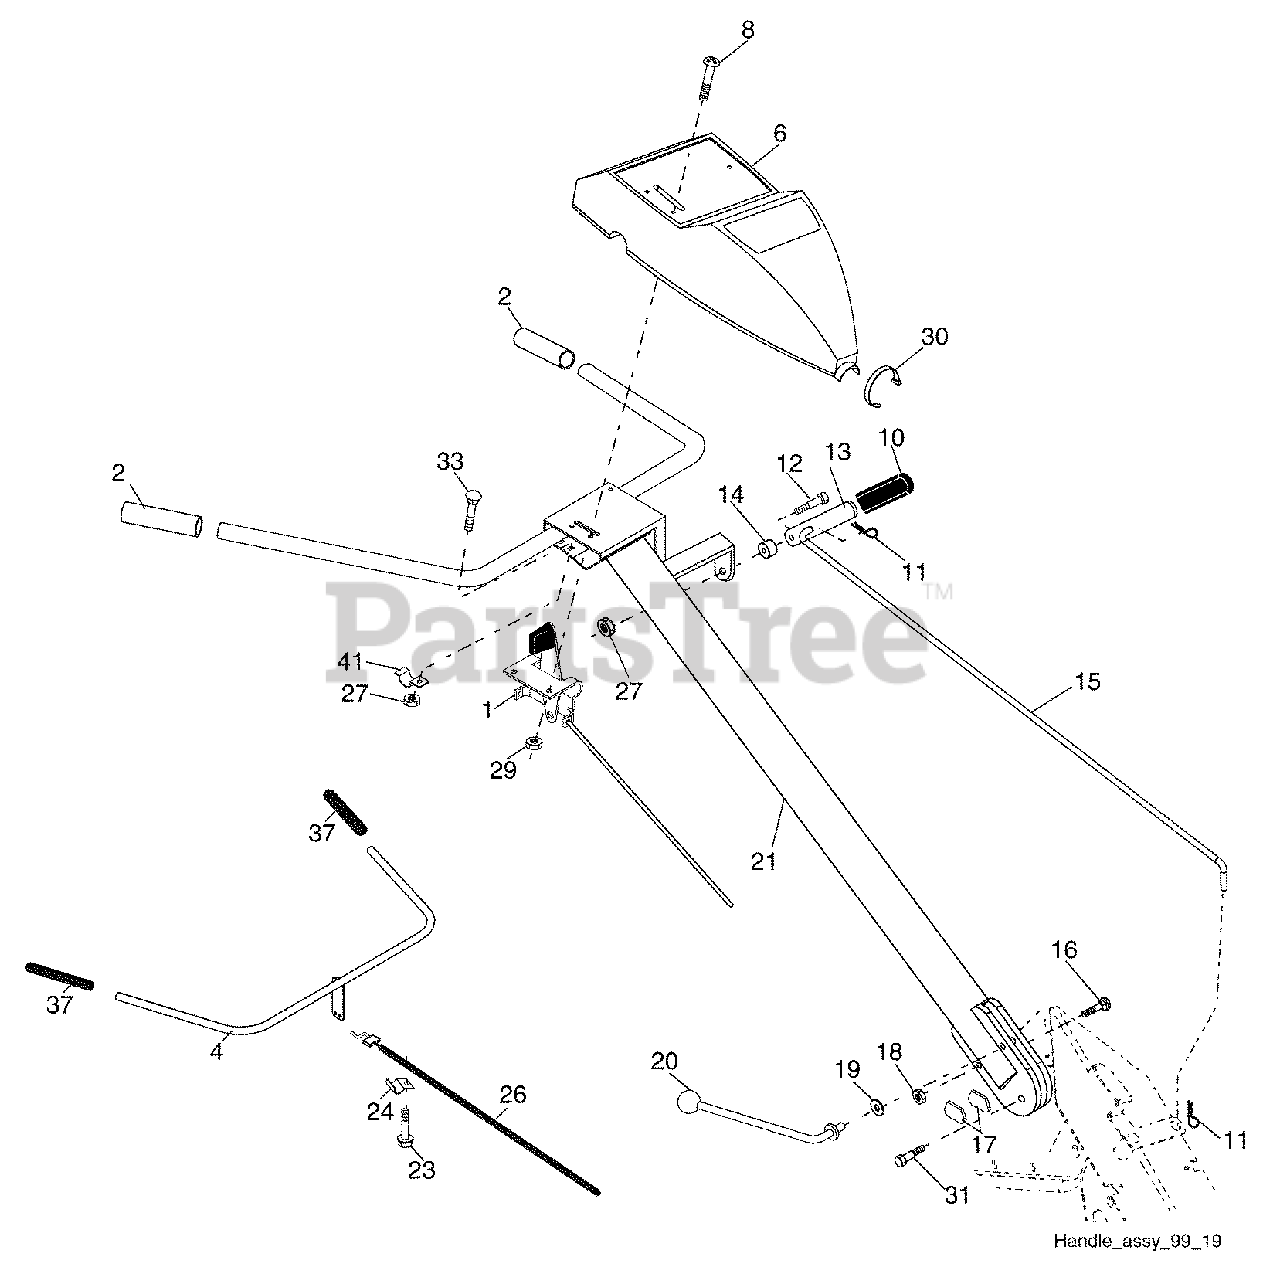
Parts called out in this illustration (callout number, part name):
1	Control, Throttle
2	Grip, Handle
4	Bar Assembly, Control
6	Panel, Control
8	Screw, Truss Hd. #10-24 unc x 1/2
10	Grip, Handle
11	Clip, Hairpin
12	Bolt, Shoulder
13	Handle, Shift
14	Grommet, Rubber
15	Rod, Shift
16	Bolt, Carriage 3/8-16 x 1 Gr. 5
17	Lock, Handle
18	Nut, Crownlock 3/8-16 unc
19	Washer 13/32 x 1 x 11 Ga.
20	Lever, Lock, Handle
21	Handle
23	Screw, Hex Washer SLT#10-24 x .50
26	Cable, Clutch
27	Nut, Hex Flange 1/4-20 unc
29	Nut, Keps #10-24 unc
30	Tie, Cable
31	Bolt, Pivot
33	Bolt, Carriage 1/4-20 unc x 1/2
37	Grip, Bar, Control
41	Clamp, Bar, Control
